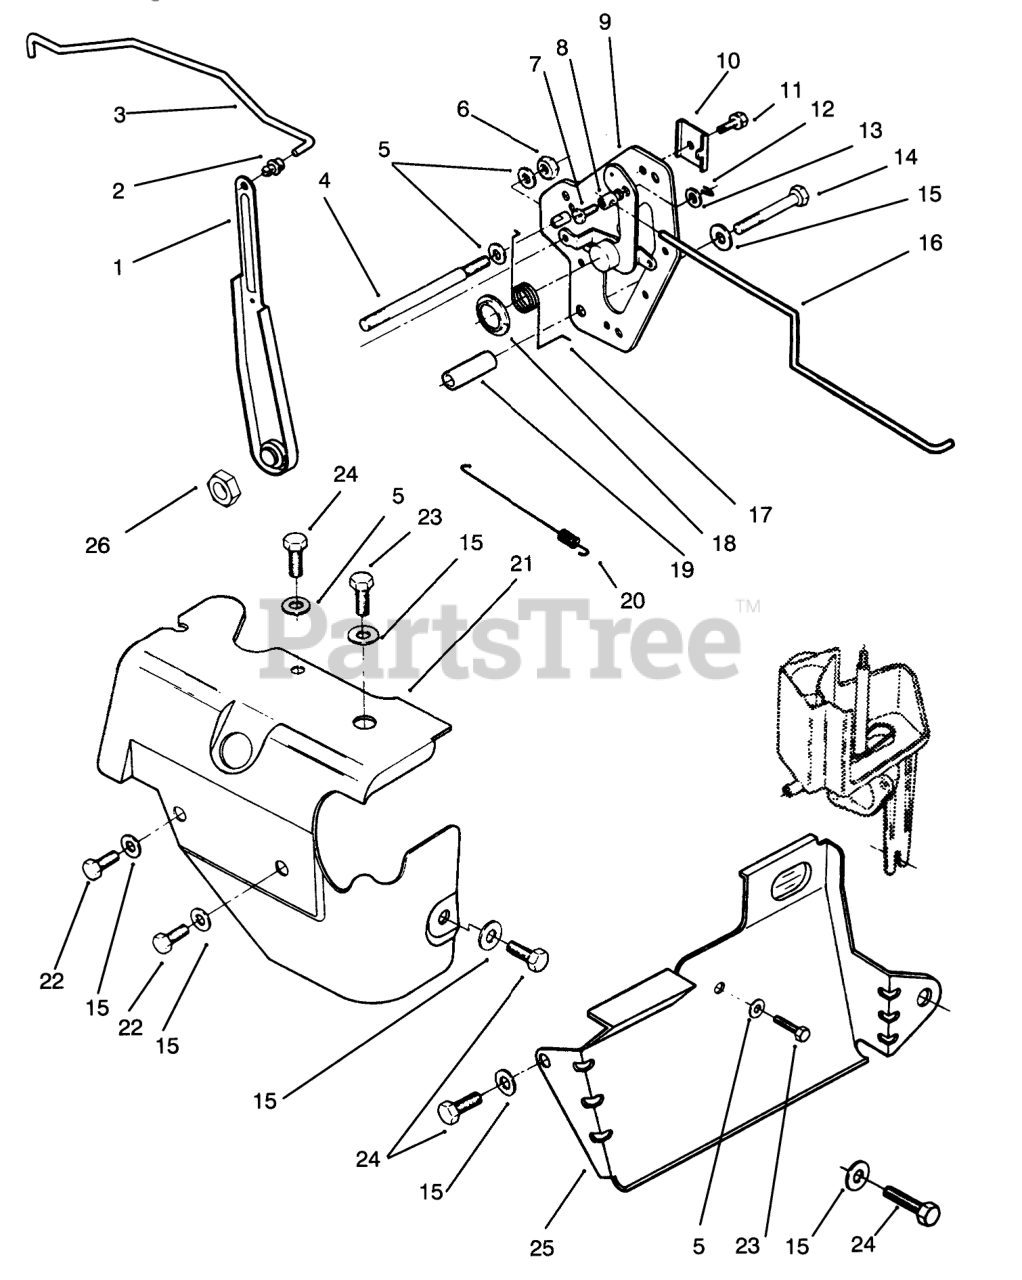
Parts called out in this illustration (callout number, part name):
1	GOVERNOR LEVER
2	LINK CLIP
3	THROTTLE LINK
5	WASHER-FLAT
6	NUT-HEX M6
7	HHMS #8-32X3/8"
8	SWIVEL-CHOKE LEVER
9	PLATE-ASS'Y THROTTLE
10	CLAMP-CONTROL
11	Bolt
12	PIN-COTTER
13	Washer
14	SCREW
15	WASHER-FLAT
16	CHOKE LINK
17	SPRING-CHOKE LINKAGE
18	RING-RETAINER
19	SPACER
20	GOVERNOR SPRING
21	Cover
22	HEX HEAD CAPSCREW
23	HHCS-M6 X 10MM
24	HHCS-M8 X 16MM
25	AIR DEFLECTOR
26	NYLON LOCK NUT
